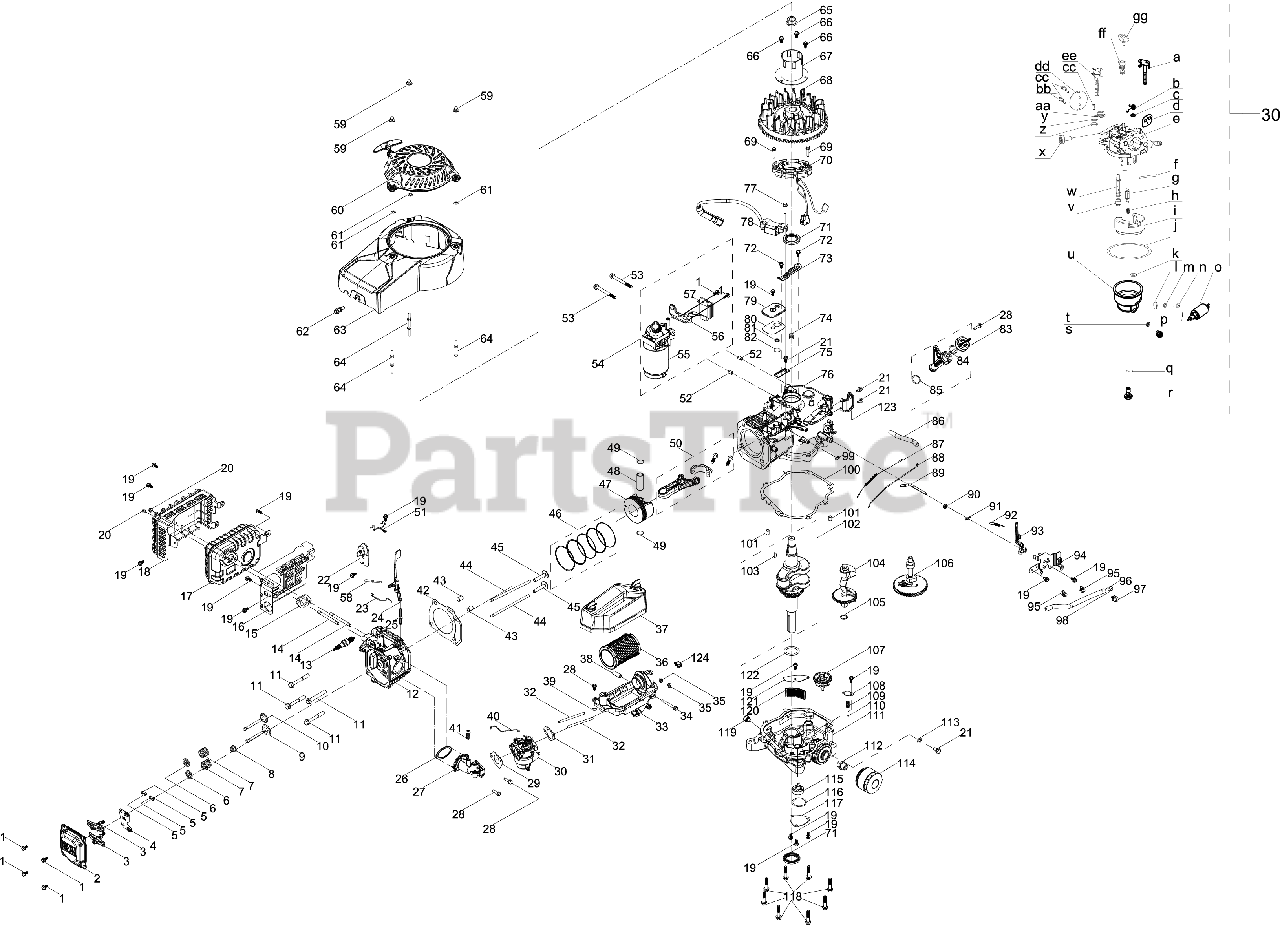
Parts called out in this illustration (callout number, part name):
1	BOLT M6 x 16
2	VALVE COVER
3	ROCKER ARM ASSEMBLY
4	ROCKER ARM BASE
5	VALVE CAP
6	VALVE SPRING SEAT
7	VALVE SPRING
8	INTAKE VALVE SEAL
9	EXHAUST VALVE
10	INTAKE VALVE
11	BOLT M10-1.25 x 70
12	CYLINDER HEAD
13	SPARK PLUG
14	STUD - M8 x 102
15	EXHAUST GASKET
16	ENGINE SHROUD
17	MUFFLER
18	MUFFLER GUARD
19	BOLT M6-1 x 14 GR8.8
20	NUT M8
21	BOLT M6-1 x 12 GR8.8
22	THERMAL SWITCH
23	THERMAL LEVER
24	AIRVANE CHOKE
25	PIVOT VANE STUD
26	O-RING 36 x 2.5
27	INTAKE MANIFOLD
28	BOLT M6 x 22
29	INTAKE GASKET
30	CARBURETOR ASSEMBLY HY-7T84AMU
31	AIR FLTER GASKET
32	STUD M6-1.00 x 92
33	AIR FILTER BASE ASSEMBLY
34	SCREW M6-1:50:CL5.
35	HEX NUT
36	AIR FILTER W/PREFILTER
36	Cub Cadet AIR FILTER W/PREFILTER
36	Genuine Factory Parts AIR FILTER W/PREFILTER
37	AIR FILTER COVER ASSEMBLY
38	BUSHING - 11X6X30
39	CARB FUEL DRAIN GASKET
40	CHOKE LEVER
41	SELF TAPPING SCREW 4.8 x 16
42	CYLINDER HEAD GASKET
43	DOWEL PIN
44	PUSH ROD - INDIVIDUAL
45	TAPPET
46	PISTON RING SET
47	PISTON
48	PISTON PIN
49	PISTON PIN SNAP RING
50	CONNECTING ROD ASSEMBLY
51	WIRE ROD
52	DOWEL PIN
53	BOLT M8-1.25 x 80
54	ELECTRIC STARTER
55	ELECTRIC STARTER ASSEMBLY
57	REGULATOR
58	IDLE SPRING
59	ACORN NUT
60	RECOIL STARTER ASSEMBLY
61	WASHER
62	HOOK BOLT
63	ENGINE BLOWER HOUSING
64	STUD - M6 x 83
65	NUT M20 x 1.5
66	BOLT M6-1 x 10 GR8.8
67	STARTER CUP
68	FLYWHEEL ASSEMBLY
69	BOLT M5 x 28
70	ALTERNATOR
71	OIL SEAL - 35X52X7
72	BOLT M5-.8 x 10
73	WIRE PLATE
74	BUSHING
75	BREATHER SCREEN
76	CRANKCASE
77	BOLT-M6-1 x 28 GR8.8
78	IGNITION COIL
79	BREATHER COVER
80	BREATHER COVER GASKET
81	BREATHER VALVE SPRING
82	BREATHER VALVE
83	DIPSTICK ASSEMBLY
84	O-RING
85	O-RING
86	BREATHER HOSE
87	THROTTLE DAMPENING SPRING
88	THROTTLE LINKAGE
89	GOVERNOR GEAR SHAFT
90	GOVERNOR SEAL
91	COTTER PIN
92	GOVERNOR SPRING
93	GOVERNOR ARM ASSEMBLY
94	CONTROL BRACKET ASSEMBLY
95	HOSE CLAMP
96	FUEL HOSE 6.3 x 12.5 x 250
97	FUEL LINE SUPPORT CLAMP
100	CRANKCASE GASKET
101	DOWEL PIN
102	CRANKSHAFT ASSEMBLY
103	FLYWHEEL KEY
104	BALANCE SHAFT ASSEMBLY
105	WASHER 17.2 x 26 x 1
106	CAMSHAFT ASSEMBLY
107	GOVERNOR GEAR
108	PRESSURE RELEASE COVER
109	PRESSURE RELEASE SPRING
110	OIL PUMP STEEL BALL
111	CRANKCASE COVER
112	SCREW JOINT OIL FILTER ADAPTER
113	WASHER - 6.2X1.5X13
114	ENGINE OIL FILTER
114	Cub Cadet OIL FILTER
114	Genuine Factory Parts OIL FILTER
115	OIL PUMP ASSEMBLY
116	GASKET
117	OIL SEPARATOR
118	BOLT M8 x 40
119	ENGINE PLUG 3/8 NPT
120	FILTER SCREEN
121	OIL SCREEN PLATE
122	WASHER - 35.4X1X52
123	LIFT HOOK
